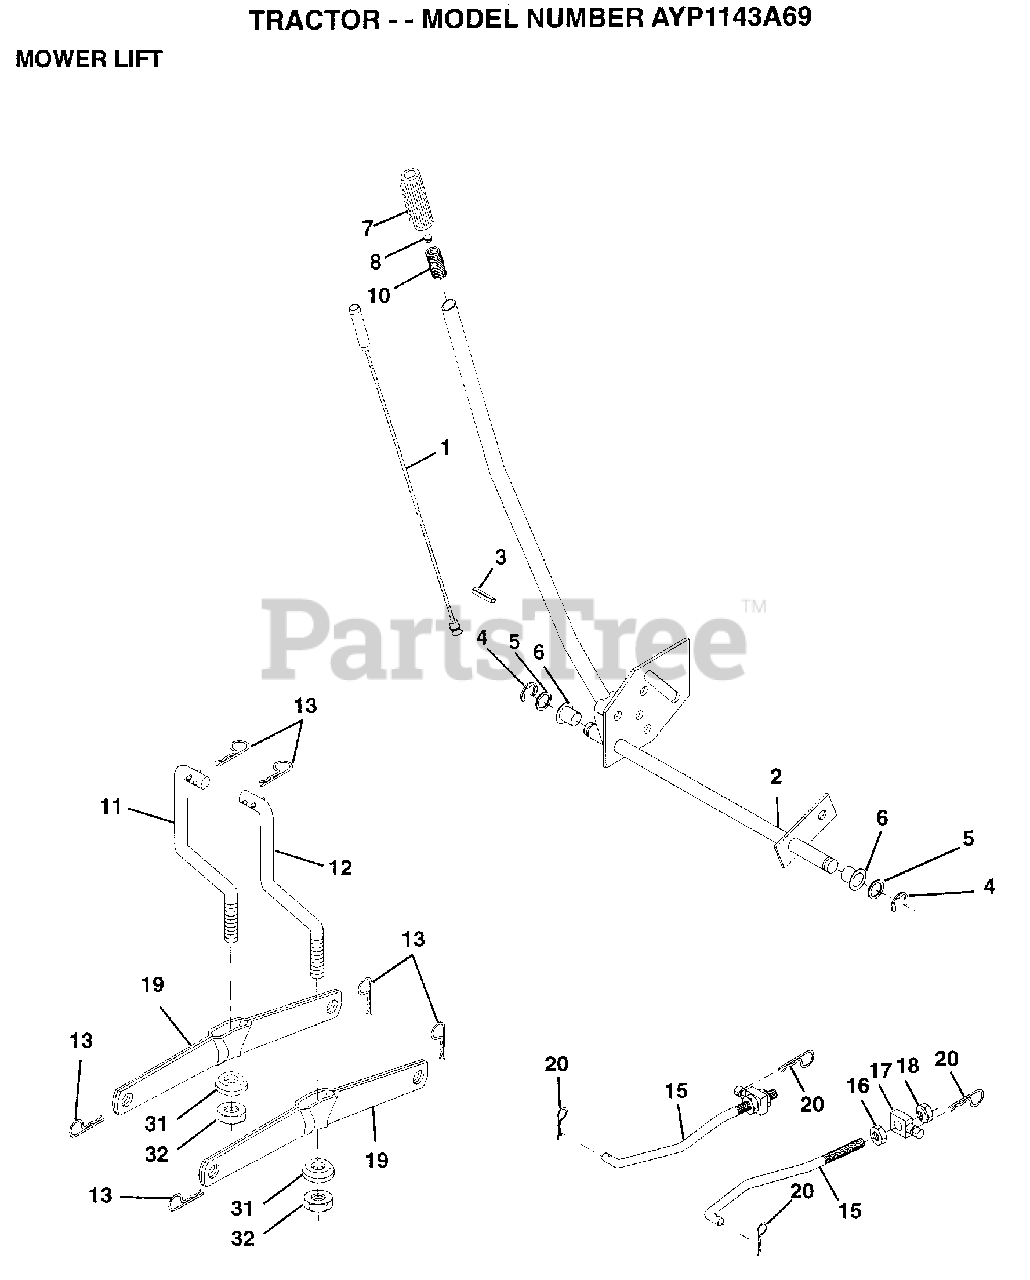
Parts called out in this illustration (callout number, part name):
1	WIRE ASM
2	HANDLE.LIFT.LH.
3	PIN GROOVE
5	WASHER
6	NYLON BEARING
7	GRIP
15	LINK.FRONT
16	NUT
17	TRUNION
18	NUT.LK.W/WSH.1/2.
19	ARM SUSP REAR
20	RETAINER.SPRING
31	BEARING PVT LH
32	NUT.CROWNLOCK.3/8
